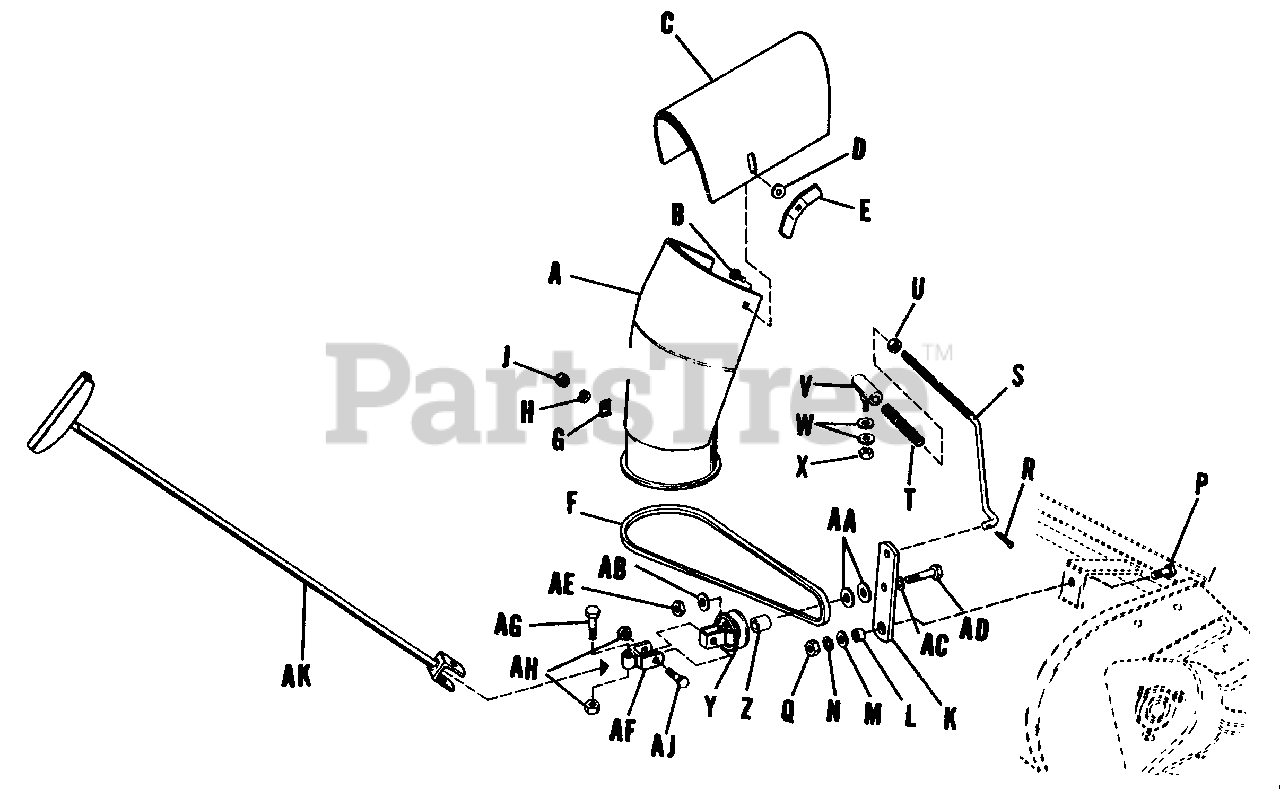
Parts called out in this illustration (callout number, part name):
A	Spout Assembly
B	Carriage Bolt, 5/16"-18 NC x 3/4" lg.
C	Extension, Spout
D	Washer, Plain, 3/8"
E	NUT, Wing, 5/16-18
F	Belt, "V" (Spout)
G	Clamp. Spout Belt
H	Washer, Lock, 5/16"
J	Nut, Hex, Full, 5/16"-18 NC
K	Lever, Idler Pulley
M	Washer, Plain, 3/8"
N	Washer, Lock, 3/8"
P	Capscrew, Hex, 3/8"-16 NC x 1" lg.
Q	Nut, Hex, Full, 3/8"-16 NC
R	Rod, Belt Tightener
S	Pin, Cotter, 3/32" x 3/4" lg.
U	Nut, Hex, Full, 3/8"-16 NC
V	Socket Assembly, Rod
W	Washer, Plain, 5/16"-18
X	Nut Lock, Full, Hex, 5/16"-18 NC
Y	Pulley Assembly
AB	Washer, Plain, 5/16"
AC	Washer, Lock, 3/8"
AD	Capscrew, Hex, 3/8"-16 NC x 1-3/4" lg.
AE	Nut, Hex, Full, 3/8"-16 NC
AF	Fork Assembly
AG	Capscrew, Hex., 5/16"-18 NC x 1-1/2" lg.
AH	Nut, Hex, Full, Lock, 5/16"-18 NC
AJ	Capscrew, Hex, 5/16"-18 NC x 1-3/4" lg.
AK	Handle Assembly, Adjusting
